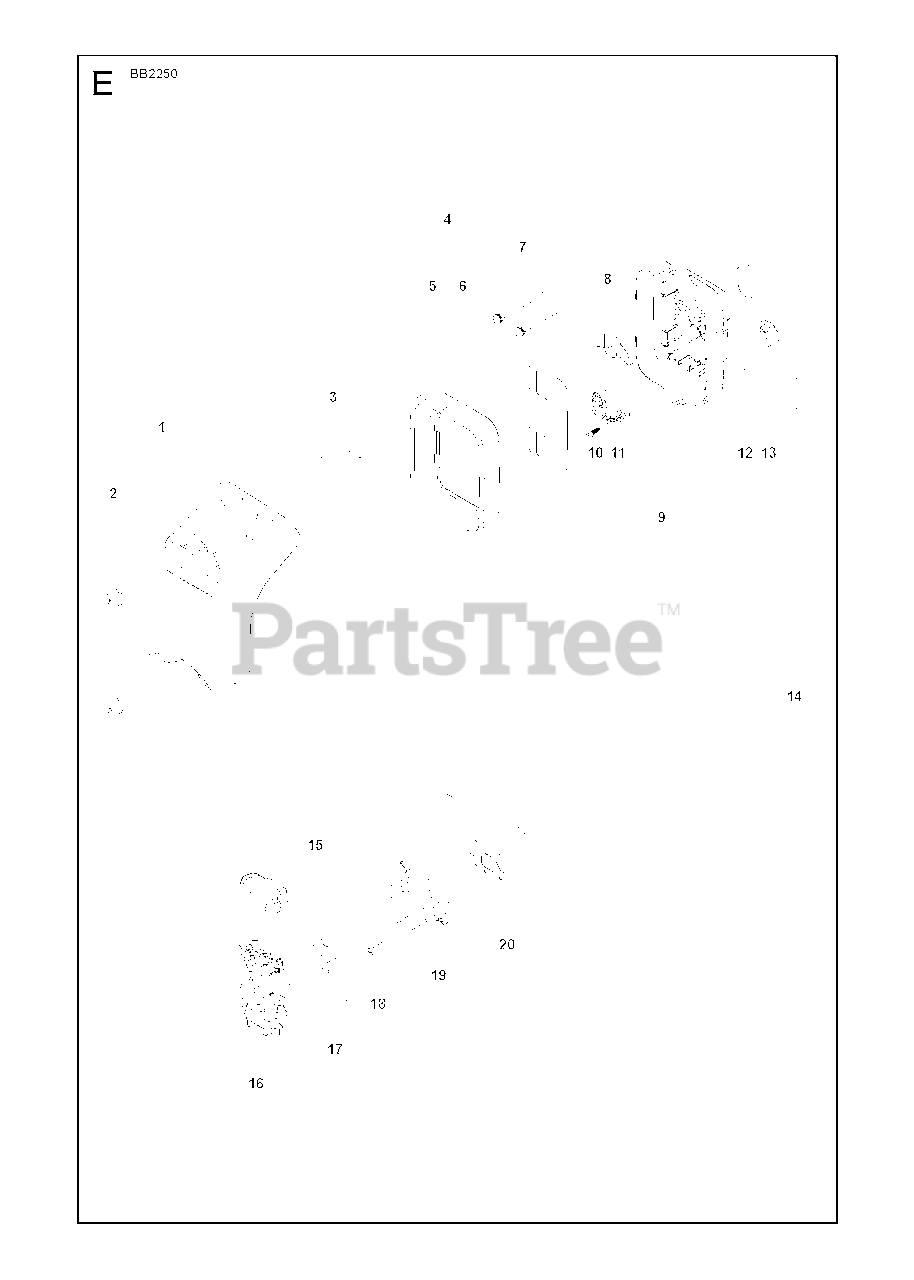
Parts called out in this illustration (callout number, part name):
1	COVER ASSY.
2	KNOB
3	AIR FILTER
9	CARBURETOR BODY
14	RP_LABEL,CHOKE
15	COVER
16	CARBURETOR
18	RP_BOLT
19	INSULATION
20	GASKET,INSULATOR
